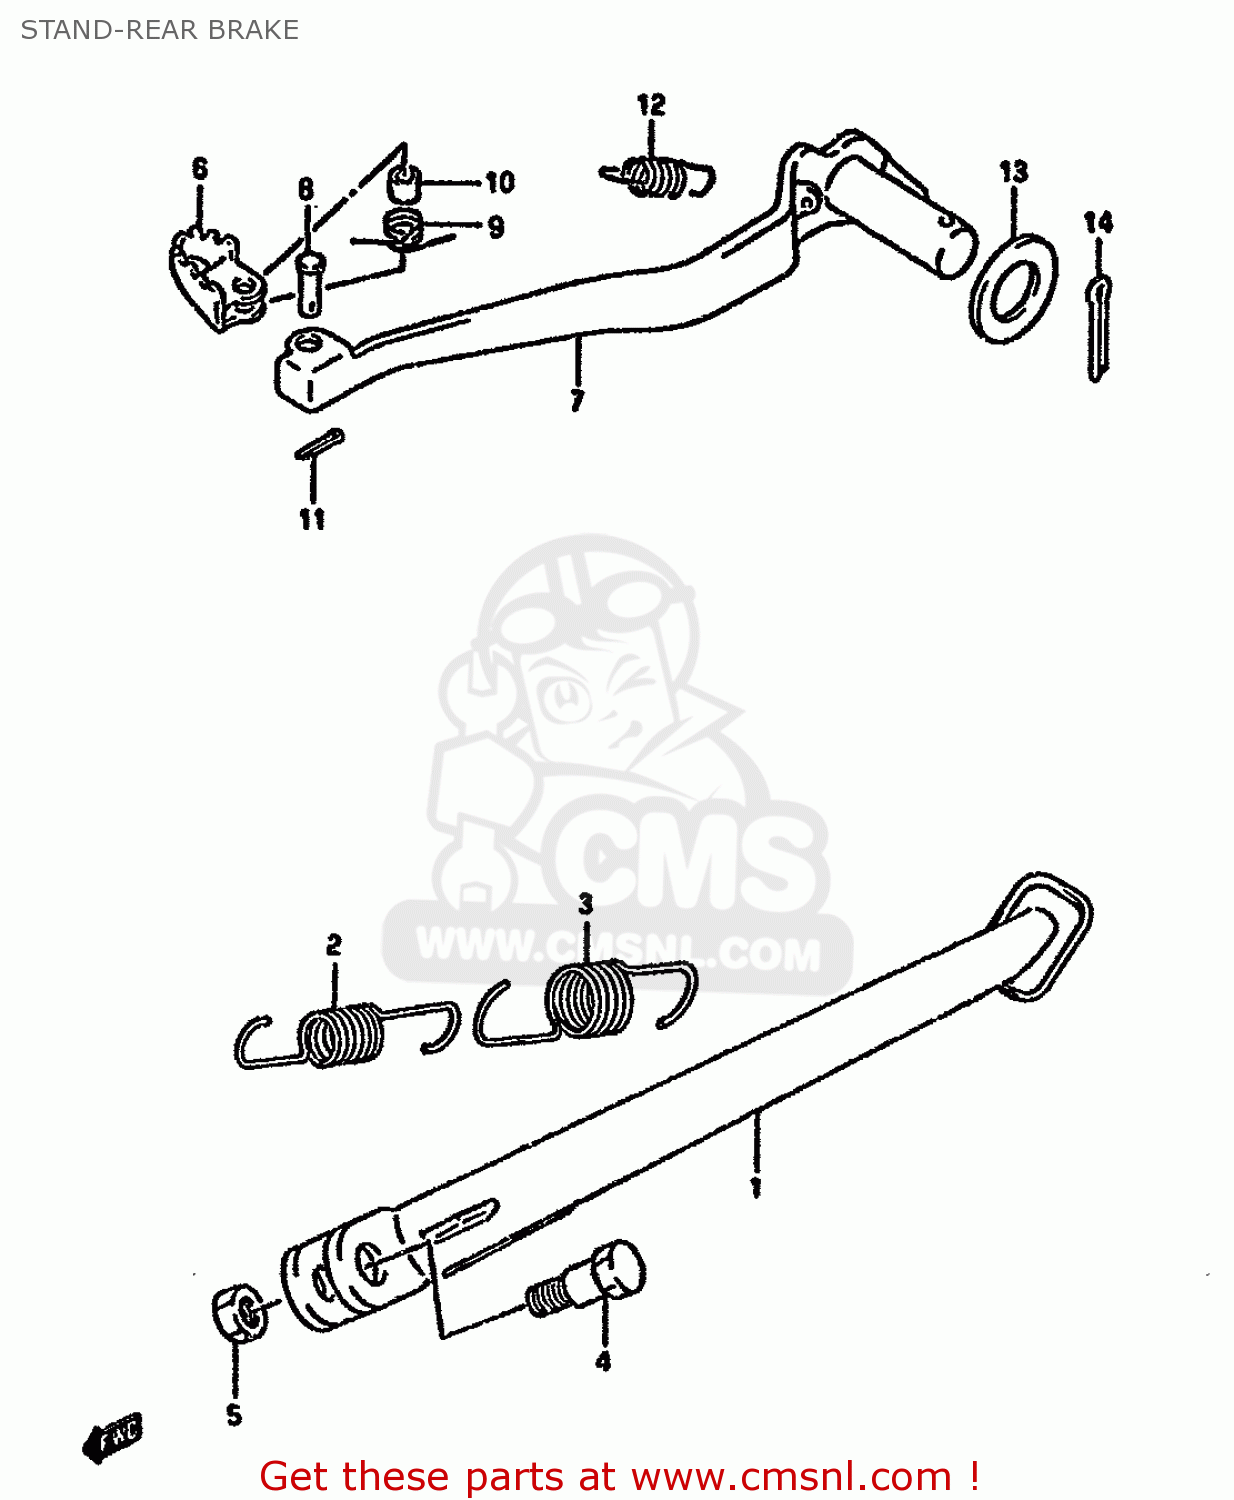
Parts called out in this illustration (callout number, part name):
1	STAND,SIDE
2	SPRING
3	SPRING
4	BOLT(10X30)
5	NUT
6	PEDAL,BRAKE
7	ARM,BRAKE PEDAL
8	PIN
9	SPRING
10	SPACER(9.2X9X6.5)
11	PIN
12	SPRING
13	WASHER (17.6X34X2)
14	COTTER PIN
